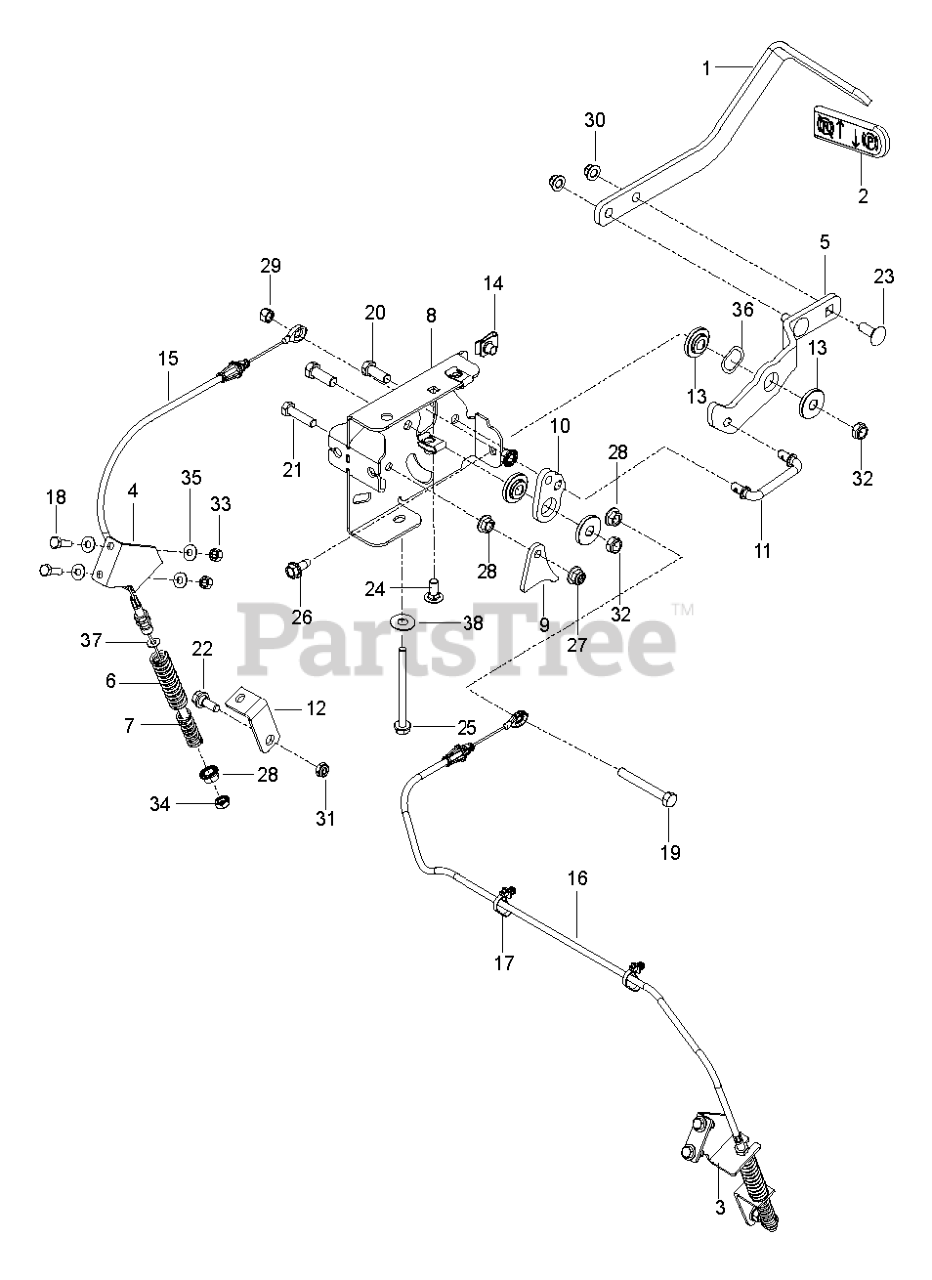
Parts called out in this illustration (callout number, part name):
1	ARM, BRAKE
2	GRIP, PARK BRAKE
3	BRKT, BRAKE RT, BLK
4	BRKT, BRAKE LT, BLK
5	LEVER.PNT.BRAKE.E-DIP
6	SPRING, RETURN
7	SPRING, ENGAGEMENT
8	MOUNT.BRAKET.PNT.BLACK.MS431
9	ACTUATOR, SWITCH
10	BELLCRANK, BRAKE
11	LINKAGE, BRAKE
12	BRKT, BRAKE, BLK
13	BUSHING, BRAKE
14	U-CLIP 5/16-18 NUT RETAINER
15	CABLE.ASSY.BRAKE.CABLE.SHORT
16	CABLE.ASSY.BRAKE.CABLE.LONG
17	TIE WRAP, 8-3/8", W/CLIP
18	HCS 1/4-20X7/8 GR5
19	HCS 5/16-18 X 2 1/2 TPBLT
20	HCS 3/8-16X1.GRD.5.ZD
21	HCS 5/16C X 1
22	BOLT, SHOULDER
23	BOLT D
24	BOLT 5/16C X 3/4" CARRIAGE
25	HHFS 5/16-18 X 3 3/4
26	HHFS 5/16-18 X 3/4
27	5/16-18 NYLOC FLANGE NUT
28	NUT 5/16C WHIZ
29	NUT 5/16 NYLOC
30	NUT 3/8-16 HEX FLG NYLOC ZD
31	NUT.71038.31-18.HEX.NYLOCK
32	NUT HEX 3/8-16 NYLON, THIN
33	NUT.1/4-20.HEX.NYLOC.ZD
34	NUT 5/16-18 HEX JAM ZD
35	WASHER 1/4 SAE
36	WASHER, .825 X 1.087, WAVE
37	WASHER 3/8 SAE FLAT
38	WASHER.9/16 X 1 3/8 X 12 GA.
